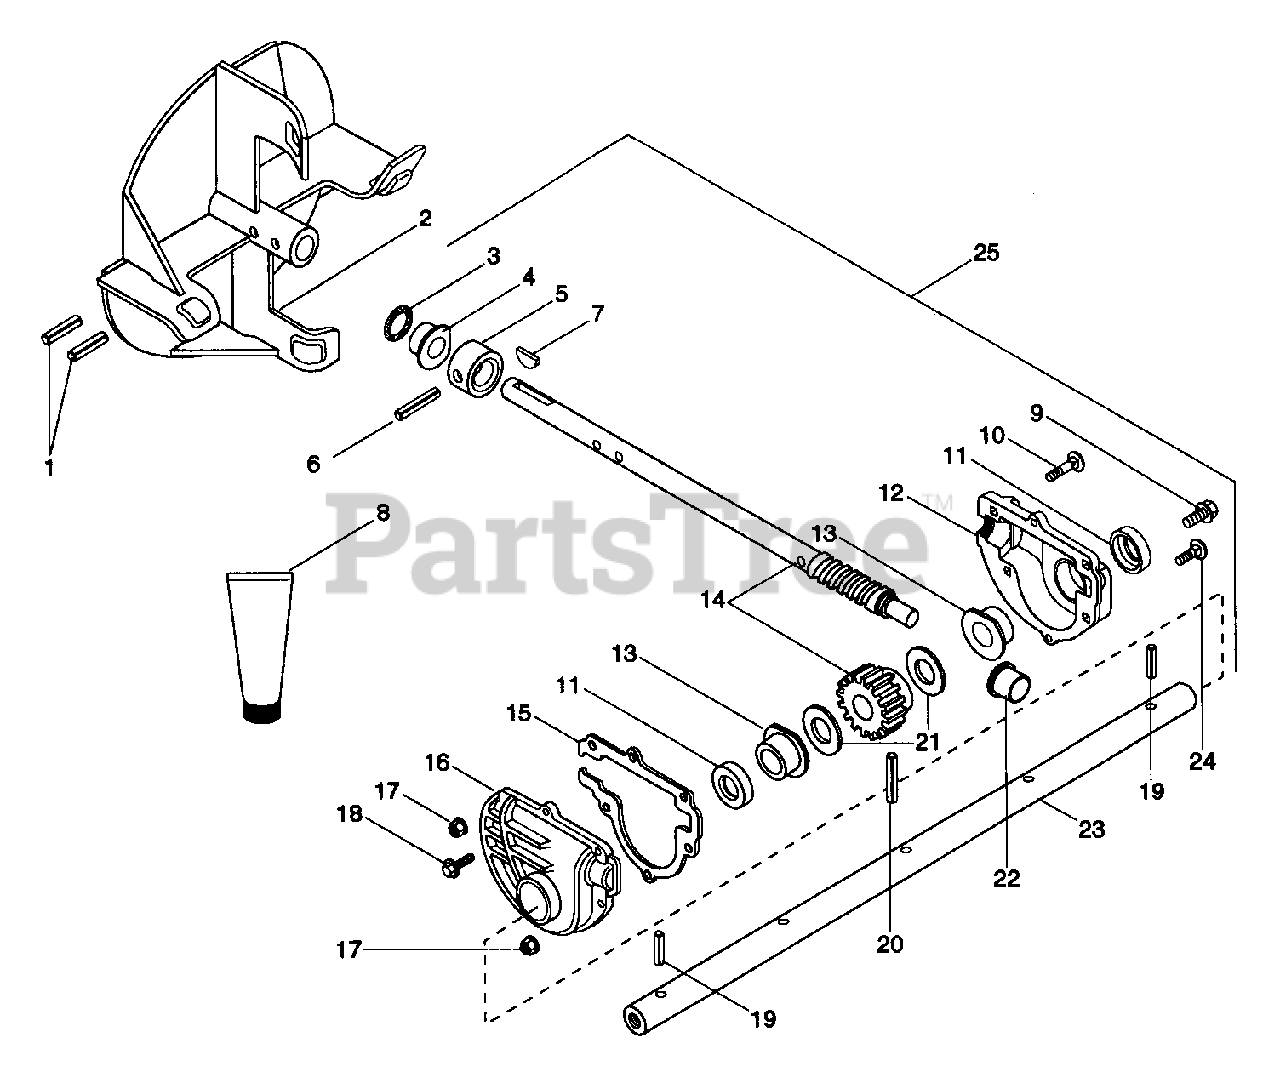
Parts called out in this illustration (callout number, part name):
1	PIN-ROLL .250X1.75
2	FAN - 12"
3	O-RING .250X.943X.103
3	SEAL .750X1.000X.125
4	BSHG-FLG .750X1.000X.750X1.250
5	THRUST COLLAR
6	PIN-GRV .188X1.25 TP A
7	KEY-WDRF .188X.875X.375 SAE11
8	8 OZ TUBE OF LIQUID GREASE
8	ARIENS 16 OZ.BOTTLE OF L2 LUBE
9	SCR-TAP .375-16X .50 HWH PL TR
10	BLT-RDHDSQNK .25-20X1.25 GR5PL
11	SEAL 1.000X1.312X.150
12	GEAR CASE HALF L H
12	L. H. GEAR CASE HALF
13	BSHG-FLG1.000X1.12X.62X1.50BR
14	WORM SHAFT & GEAR ASSY
15	GASKET
16	GEAR CASE HALF R H
16	R. H. GEAR CASE HALF
17	NUT-LK-FLG .250-20 PL
18	SCR-TAP 10-24X.75 HWH PL TR
19	PIN-ROLL .188X1.50
20	PIN-GRV .313X1.44 TP C
21	WSHR-HRD-THRS 1.007X1.542X.062
22	BSHG-FLG .500X.750X.750X1.000
23	SHAFT, RAKE - 24"
24	BLT-RDHDSQNK .25-20X.88 PL
25	GEAR CASE - 24" - ALUMINUM
